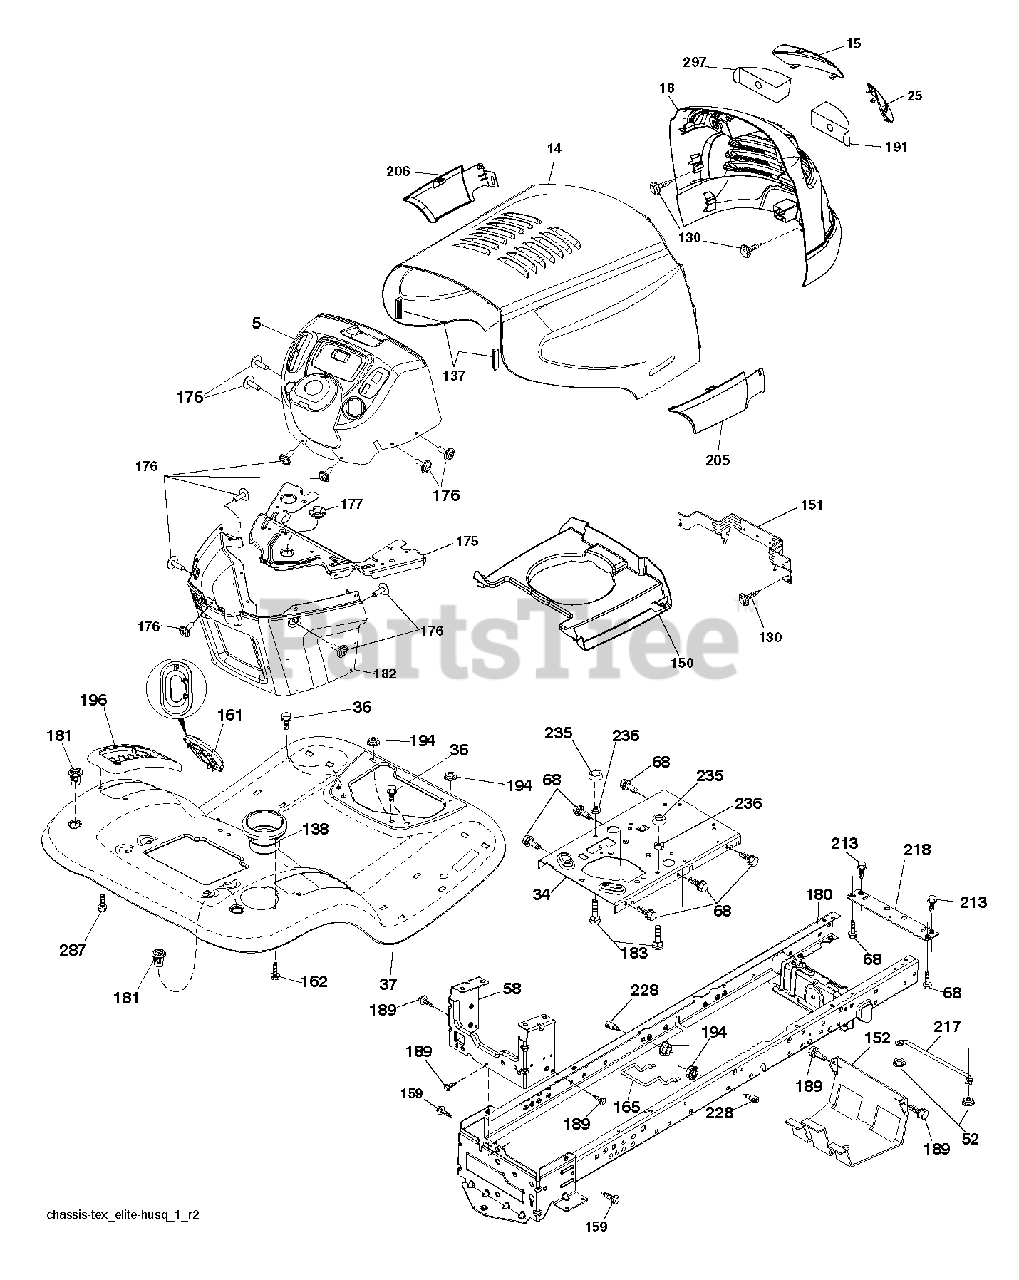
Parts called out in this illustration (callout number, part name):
5	DASH UPPER
14	HOOD.PNT.ELITE.TVENT.SVENT.SSK
18	GRILLE.ELITE HUSQ.BLACK.DL.
36	SCREW 5/16"
52	LOCKNUT
58	DRAWBAR UPPER 2PC SMALL FENDER
68	SCREW LT
130	SCREW.#10 X 0.750.BOS (2 2)
137	BUMPER.HOOD.LARGE.1.75"
138	CUPHOLDER.TL.TEX.BLACK
150	AIR DUCT
151	BRACKET PIVOT
152	SHIELD.BROWNING.W/TEX
159	SCREW, 3/8-16X3/4
161	WINDOW.FUEL.LT.TEX.BLACK
162	SCREW.HI-LO.CONSOLE
165	SUPPORT.TANK.REAR.W/TEX
175	CROSSMEMBER.LT
176	SCREW.#10-24X5/8.RN.QU
177	BUSHING,STEERING
180	CHASS.WLDMNT.TL.12GA/2P.48/54
181	FEND/FTRST.PCH.CPH.NFW
182	DASH.LOWER.LT.CCS
183	BOLT.5/16-18X1-1/4 FULL THD
189	SCREW
191	INSERT.REFLECTIVE.RH.
194	NUT LOCK HEX FLANGE 5/16-18
196	CONSOLE.ASM.DECKLFT.BL/RBT.TLT
205	SKIRT.SIDE.RH.ELITE.HUSQ.428
206	SKIRT.SIDE.LH.ELITE.HUSQ.BLACK
213	BOLT
217	ROD.PIVOT.HOOD
218	X-PIECE.HOOD.STOP.NON/
228	STUD.FASTNER.W/ANTI-ROTATE
235	SPACER FENDER
236	NUT.CENTERLOCK.5/16-
287	SCREW 1/4X20
297	INSERT LENS
